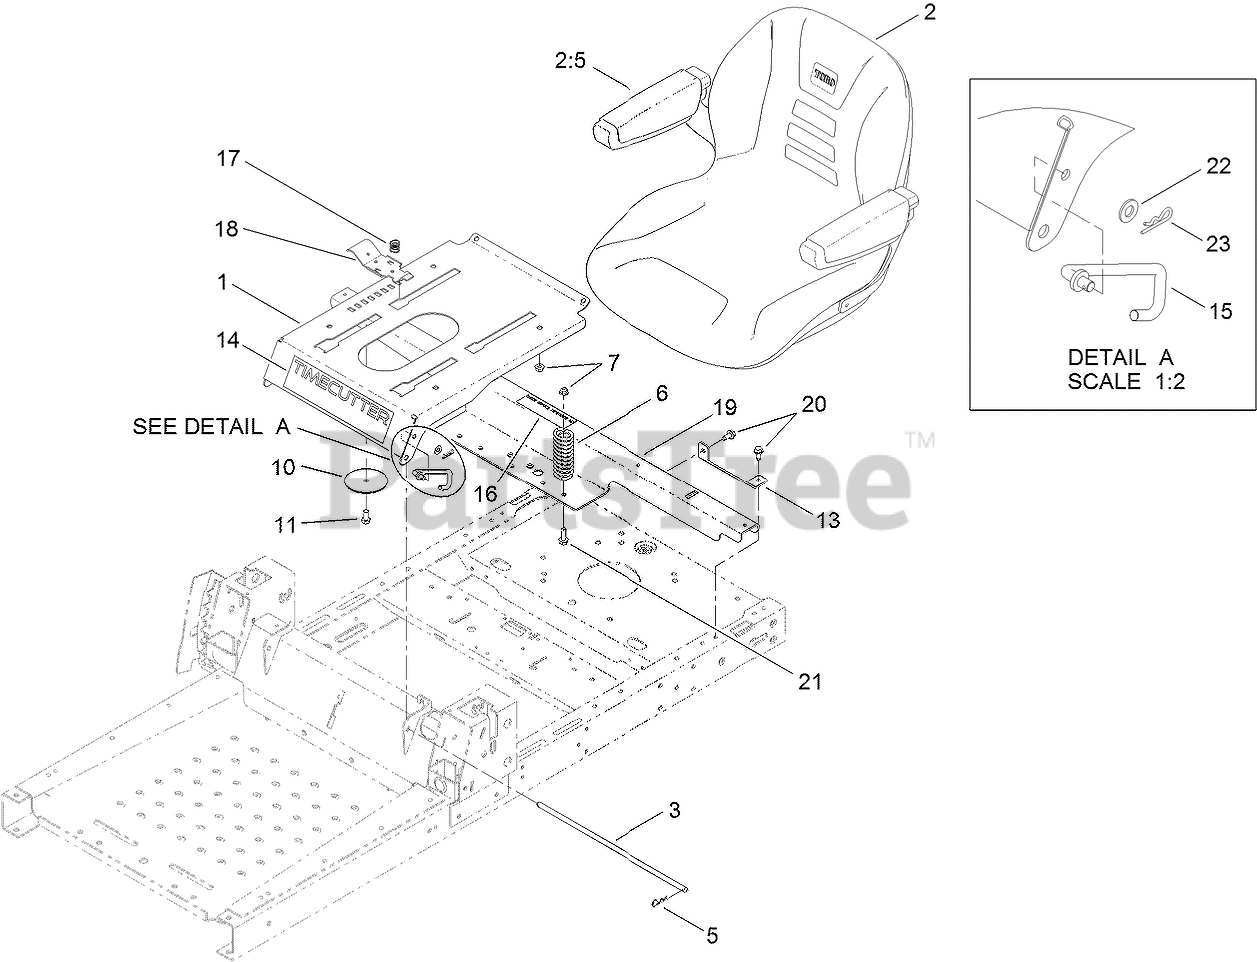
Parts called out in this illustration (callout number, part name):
1	PAN-SEAT
2	18 INCH SEAT ASM
2:5	ARMREST KIT
3	ROD-STOP
5	PIN-COTTER
6	SPRING-COMPRESSION
7	NUT-HF, NI
10	WASHER-SEAT
11	SCREW-HH
13	SUPPORT-TANK, REAR
14	DECAL-TIMECUTTER
15	STOP-SEAT
16	DECAL-SERVICE, CE
17	SPRING-COMPRESSION
18	LATCH-SEAT
19	SUPPORT-POD
20	SCREW-HWHTF
21	SCREW-HHF
22	WASHER-PLAIN
23	PIN-COTTER
